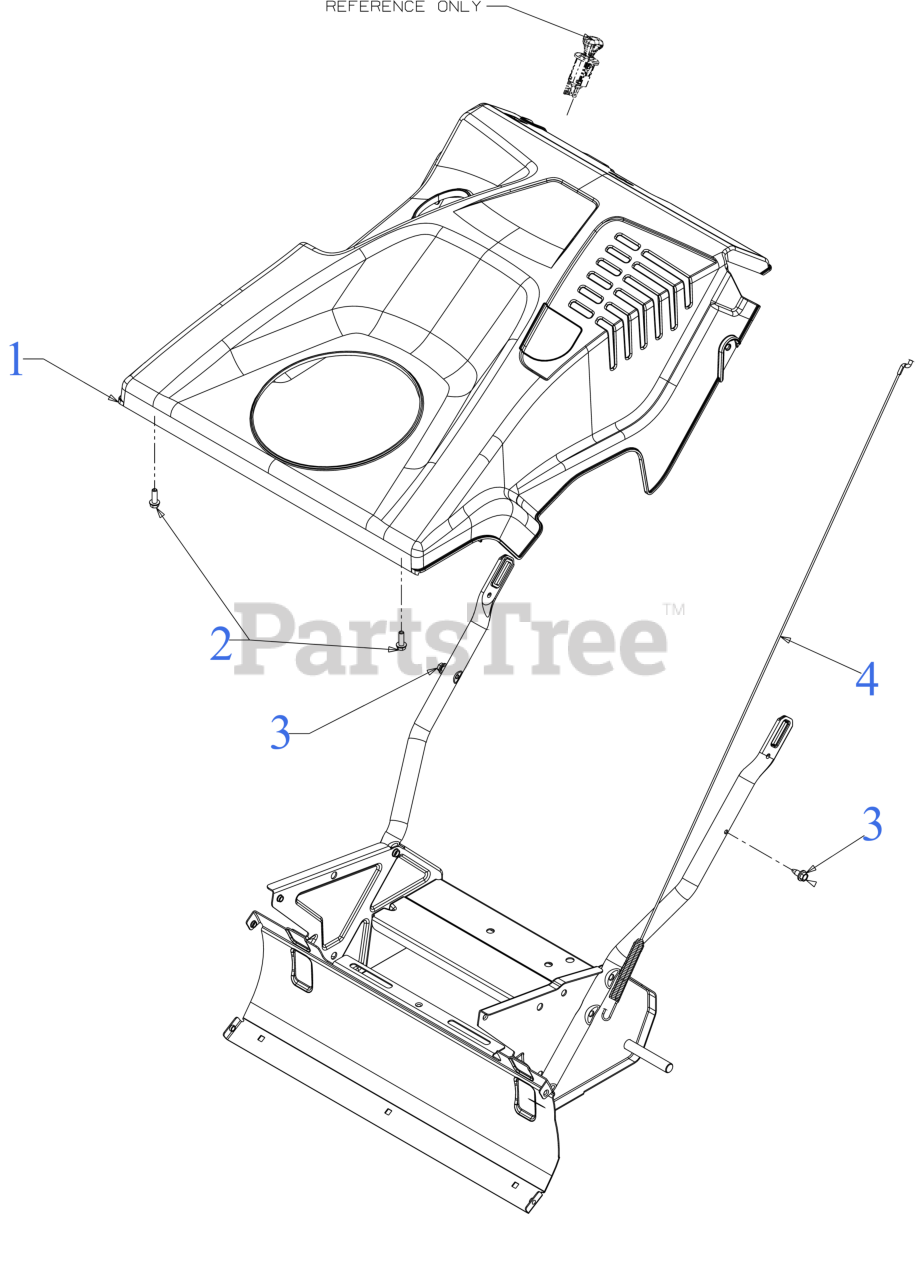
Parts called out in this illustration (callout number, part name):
1	TOP COVER KIT (W/SWITCH) (04592)
2	SCREW 1/4-15 x .750
3	SCREW 1/4-20X.625
4	CLUTCH CABLE 35.03"
